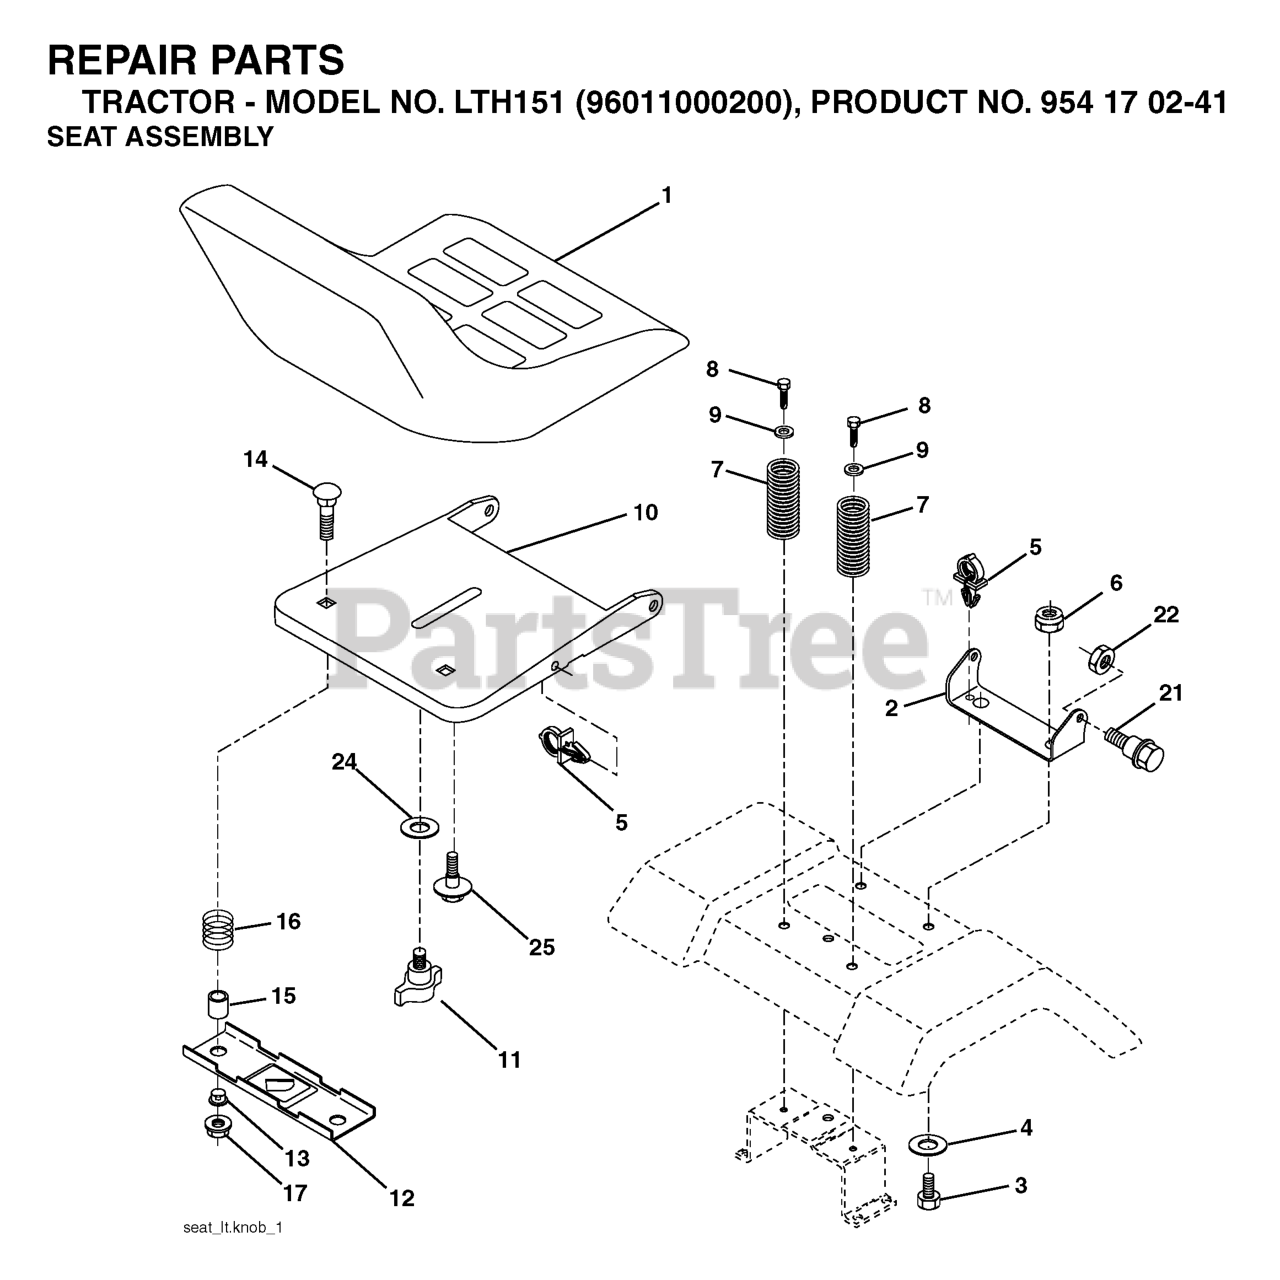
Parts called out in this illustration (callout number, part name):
1	SEAT
2	SEAT PIVOT BRKT
3	BOLT, HEX 3/8-16X1
6	NUT
7	SPRING COMPRESSION
8	SCREW 3/8-16X1
9	WASHER
10	PAN SEAT
11	KNOB.SEAT.ADJ.WINGNUT
12	BRKT SWITCH
14	BOLT.ROUND.HEAD.SQUARE.NECK
15	SPACER SPLIT 28X.96
17	NUT T
21	BOLT.SHOULDER.5/16-18
22	NUT.71038.31-18.HEX.NYLOCK
25	BOLT,SHOULD
